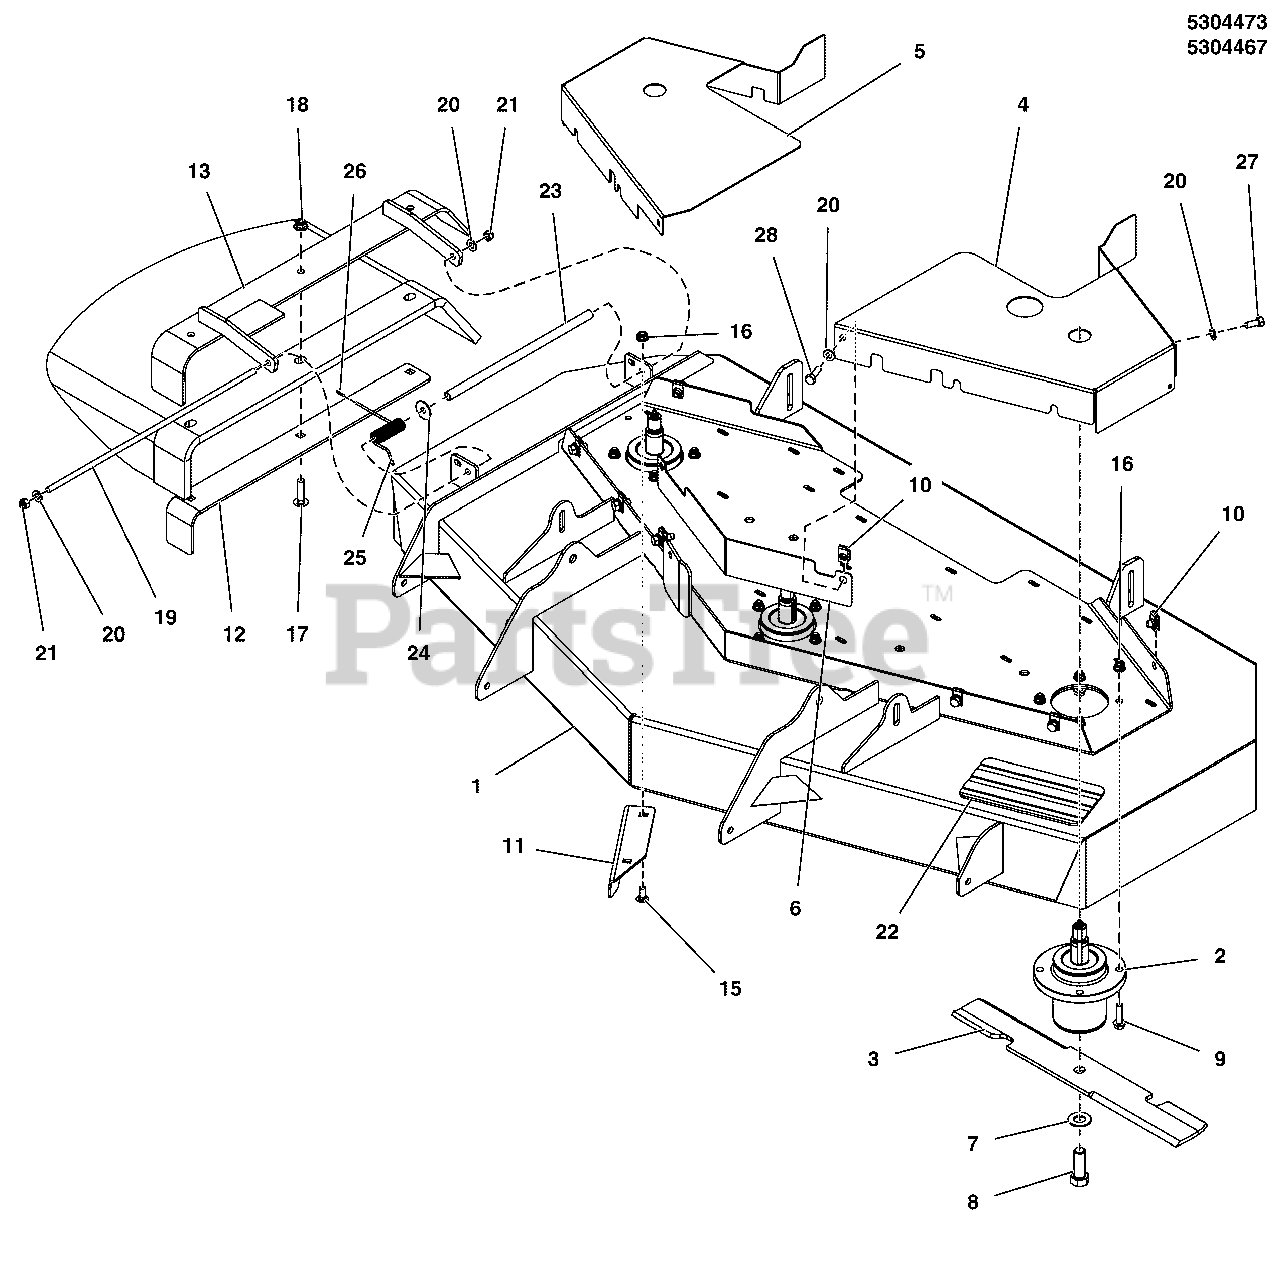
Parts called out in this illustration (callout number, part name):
1	DECK SHELL W/DECALS,52,550CE,5412827C
2	SPINDLE, ASSM, ALUMINUM - 5.25
3	BLADE, 18", SET OF THREE (3)
4	PLATE, DECK GUARD, 52, LH - ORG
5	PLATE, DECK GUARD, 52, RH - ORG
6	PLATE, DECK GUARD, 52, MD - ORG
7	WASHER, BLADE BOLT, 9/16" F436, CZ
8	BOLT, 5/8-11 X 1-3/4 GD8
9	BOLT, 5/16-18 X 1 1/4 FLANGE
10	BODY CLIP, 5/16-18-7GA MATERIAL
12	SUPPORT, DISCHARGE CHUTE - BLK
13	WELD, MOUNT, DISCHARGE CHUTE - BLK
14	CHUTE, RUBBER DISCHARGE
15	BOLT, 5/16-18 X 3/4, CARRIAGE
16	NUT, 5/16-18 HEX NYLOCK FLANGE
17	BOLT, 3/8-16 X 1-1/2, CARRIAGE, GD5, CZ
18	NUT, 3/8-16 HEX NYLOCK FLANGE
19	ROD, MOUNT, CHUTE 61, CZ
20	WASHER, 5/16 SAE
21	NUT, 5/16-24 HEX NYLON LOCK
22	SAFETY WALK, 4.00 X 7.50
23	TUBE, 1/2 X 3/8 BLACK POLY, 11.38 LG
24	WASHER, 5/16 FENDER
25	SPRING, TORSION
26	CAP, PROTECTOR, .120 ID
27	BOLT, 5/16-18 X 3/4 GD5 CZ
28	BOLT, 5/16-18 X 1 GD5 CZ
